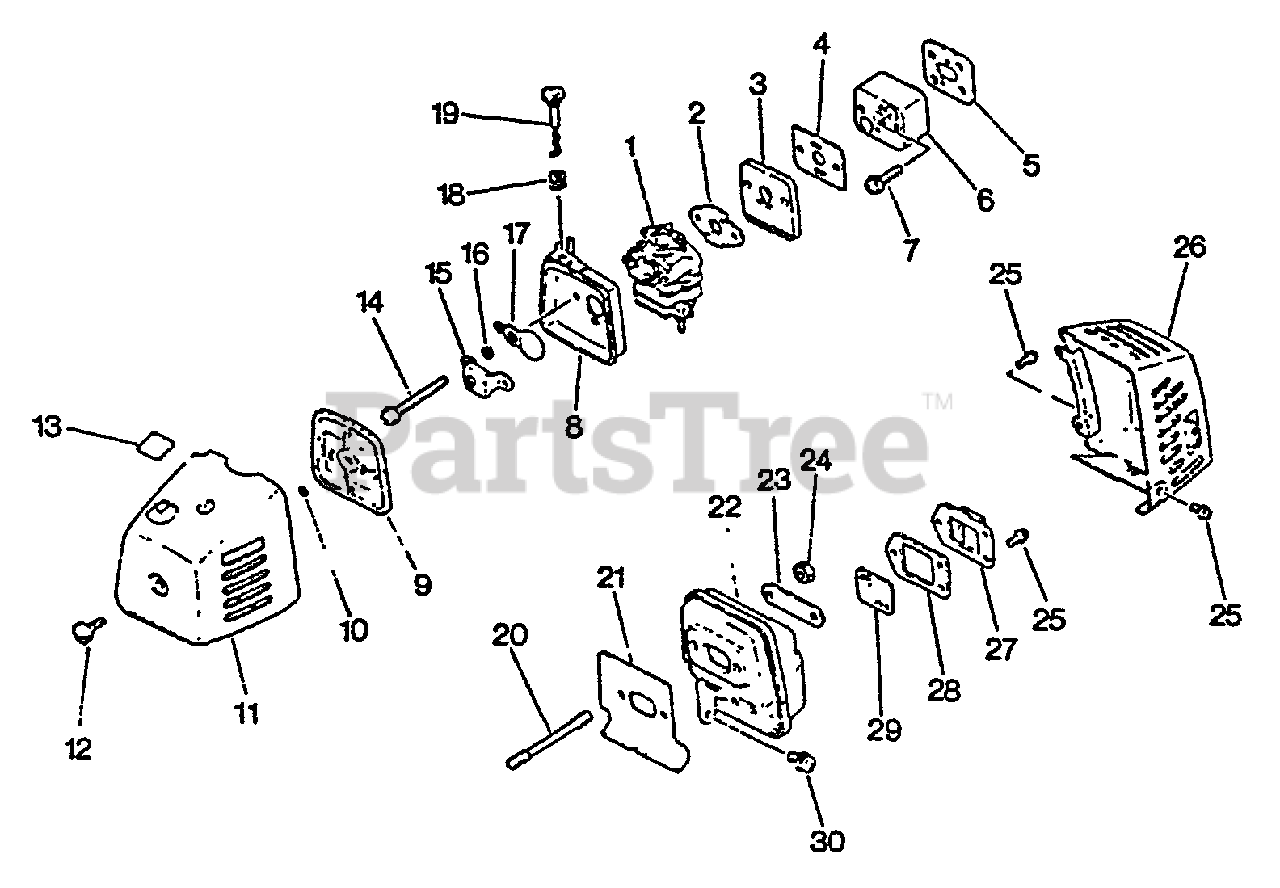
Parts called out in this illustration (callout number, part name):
1	CARBURETOR
3	PLATE
4	GASKET
5	GASKET
6	INSULATOR
7	SCREW 5×22
8	CASE, AIR FILTER
9	FILTER, AIR
11	AIR FILTER COVER ASSY
13	LABEL, CHOKE
13	LABEL - CHOKE
14	SCREW 5×50
15	PLATE, PREVENT
16	WASHER 5.2×8×0.8T
17	SHUTTER, CHOKE
18	GROMMET, CHOKE
19	ROD, CHOKE
20	BOLT, STUD
21	GASKET, MUFFLER
22	MUFFLER
24	NUT, LOCK M5
25	SCREW 4×8
26	COVER, MUFFLER
27	GUIDE, EXHAUST
28	GASKET, EXHAUST
29	SCREEN, SPARK ARRESTER
30	SCREW 5×10
